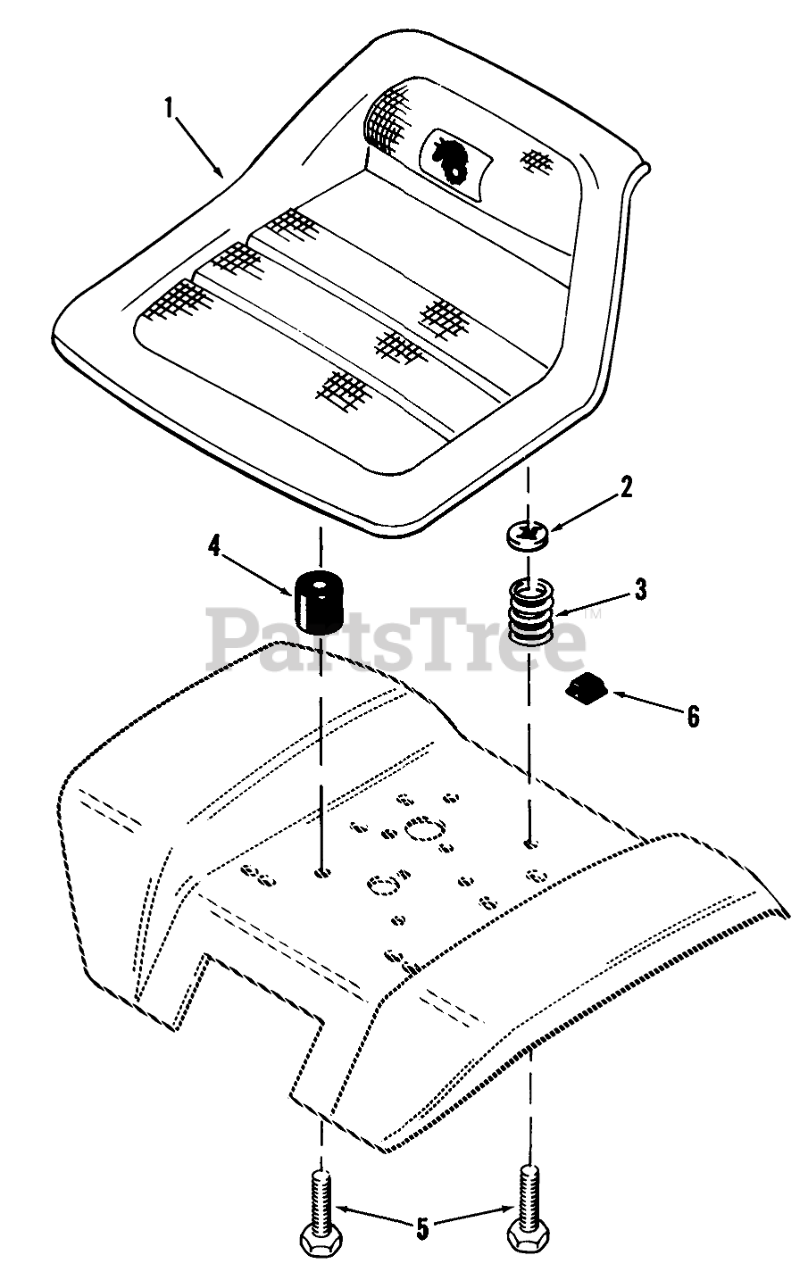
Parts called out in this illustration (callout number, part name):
1	Seat
2	NUT-PUSH
3	SPRING
4	GROMMET-RUBBER
5	SPECIAL BOLT
5	HHCS
6	BUMPER
